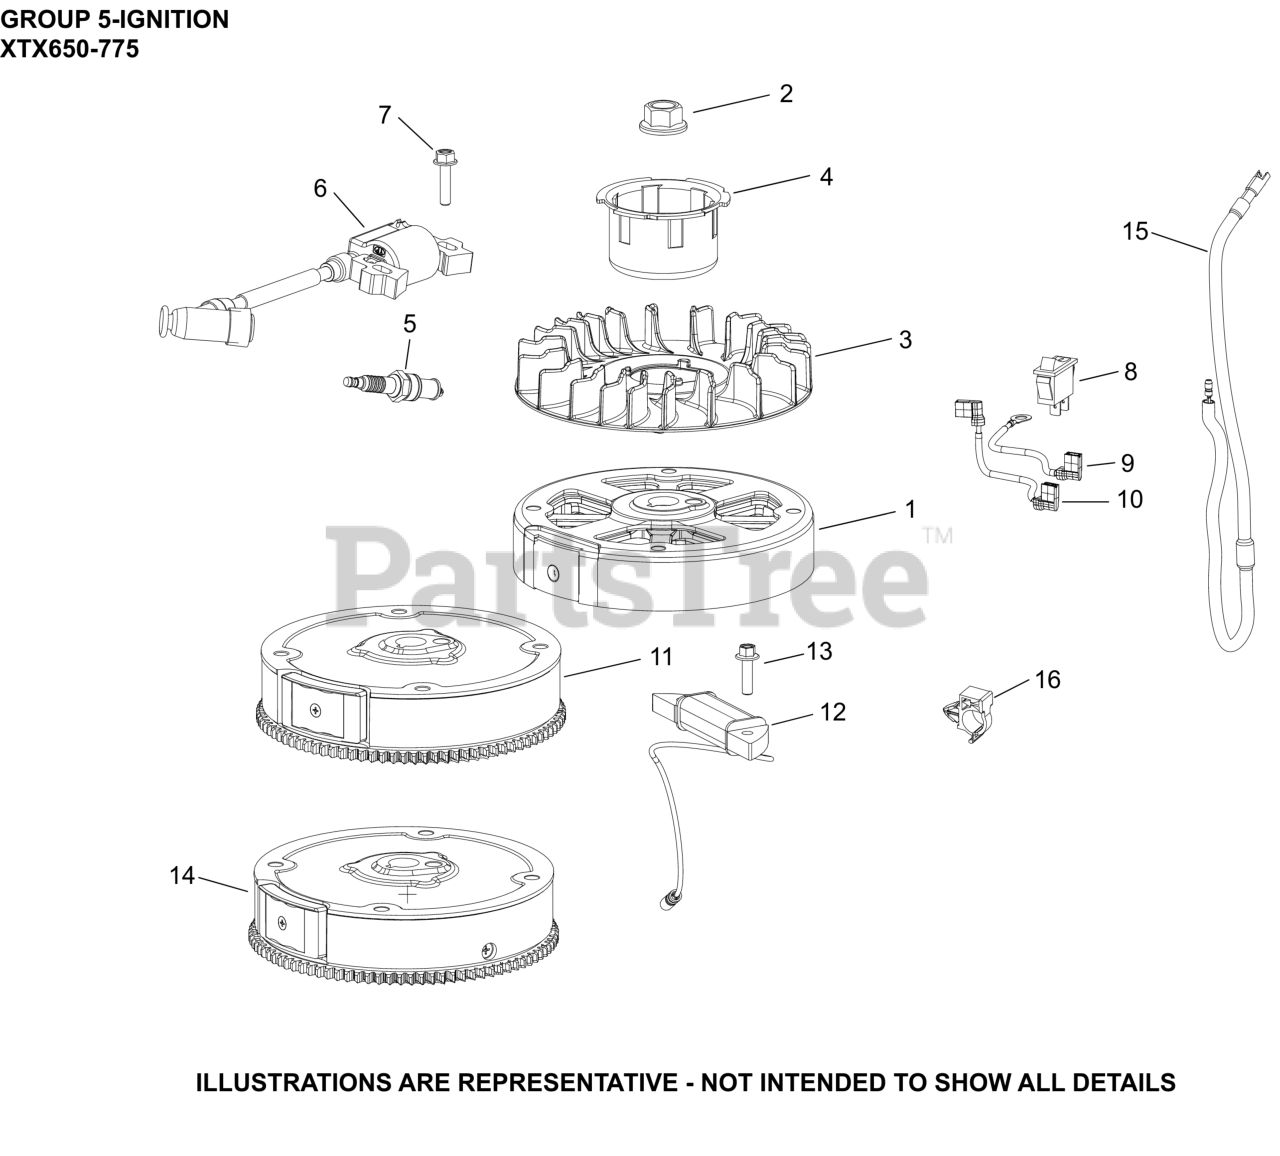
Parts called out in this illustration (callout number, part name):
1	FLYWHEEL ASSEMBLY
2	NUT, FLYWHEEL (W/SERRATIONS)
3	FAN, FLYWHEEL
4	CUP, STARTER DRIVE
5	PLUG SPARK 12MM RFI
